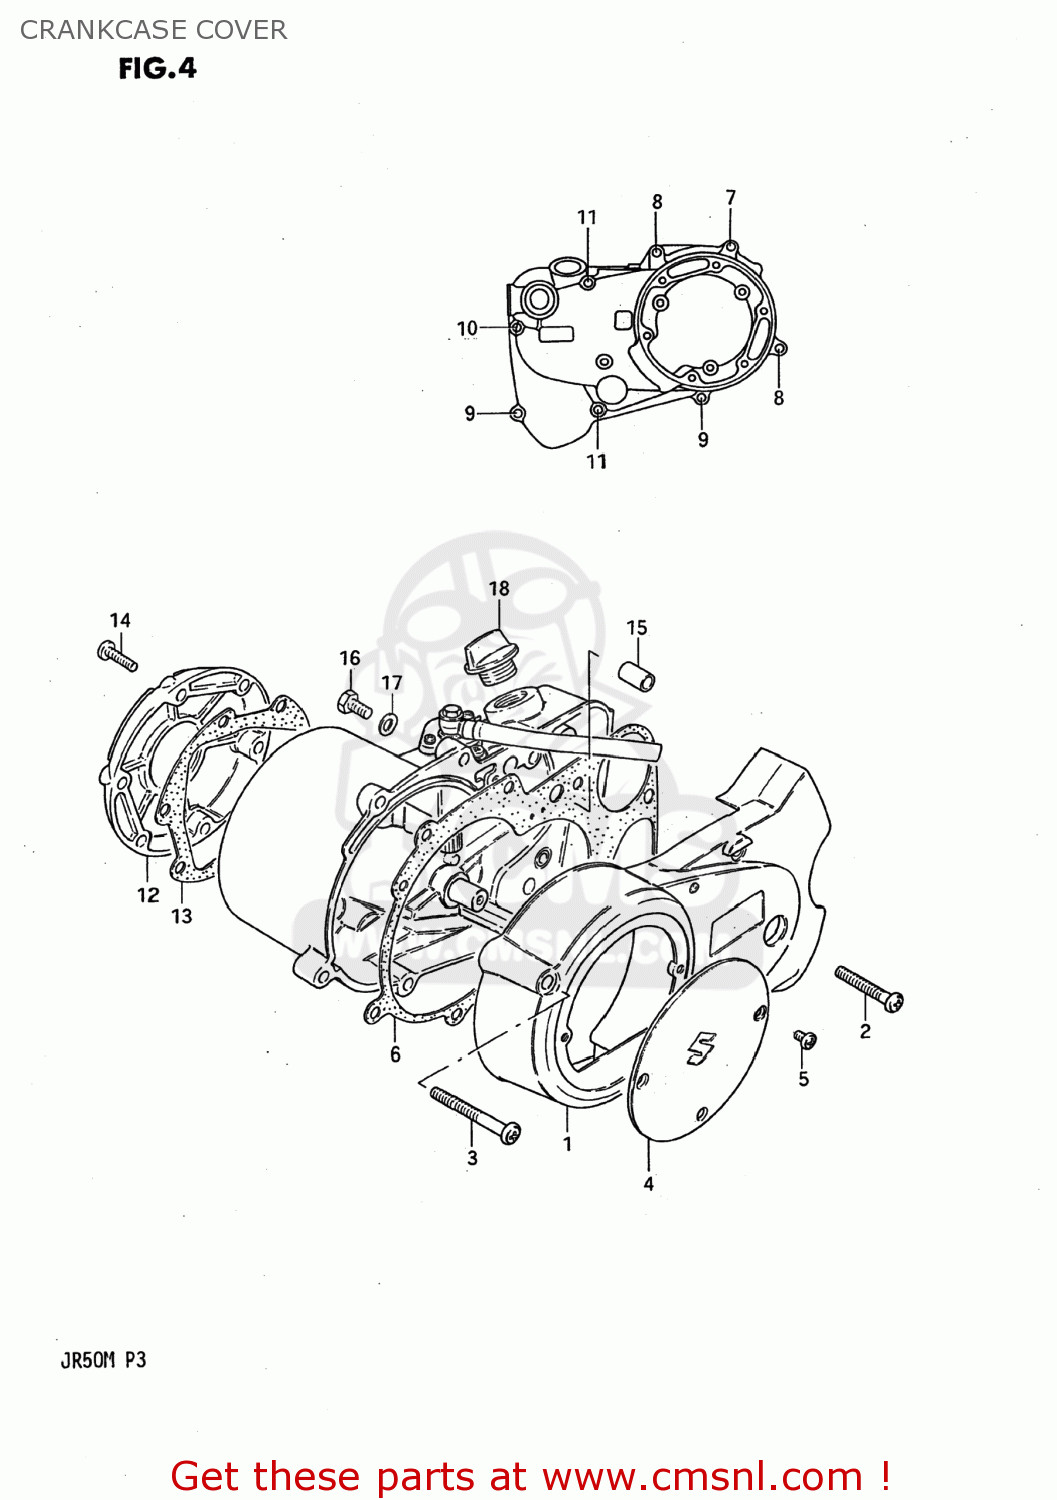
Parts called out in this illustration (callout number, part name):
1	COVER,MAGNETO
2	SCREW
3	SCREW
4	CAP,MAGNETO INSPECTION
5	SCREW
6	GASKET,CLUTCH COVER (MCA)
7	SCREW
8	SCREW
9	SCREW
10	SCREW
11	SCREW
12	CAP,CLUTCH RELEASE ADJUST
13	GASKET,CLUTCH RELEASE ADJUSTER CAP (NAS)
14	SCREW
15	PIN
16	SCREW(6X10)
17	GASKET(6.2X11X1) (NAS)
18	PLUG SET
